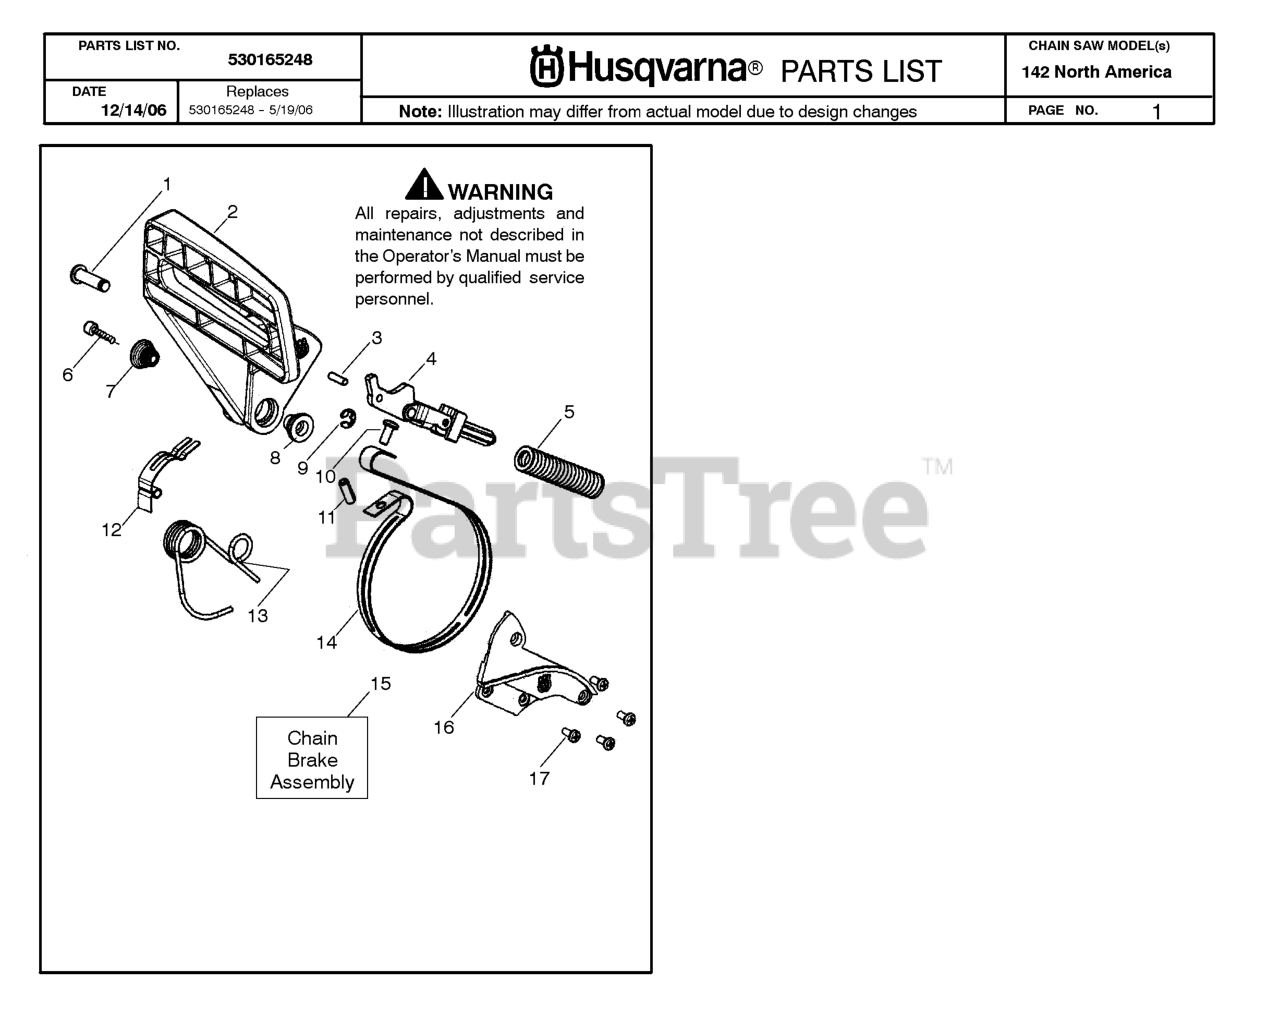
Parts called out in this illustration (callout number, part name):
4	FRONT LINK ASSY
5	%COMPRESSION SPRING
7	JOURNAL, RIGHT
8	SHAFT PIVOT
10	SCREW
12	SPRING-POSITION
13	SPRING,BRK HDL 36/41
14	BRAKE BAND
16	CHAIN BRAKE COVER
17	SCREW
530054802	CHAIN BRAKE ASM.
545090701	ASSY CHAIN BRAKE EZT
